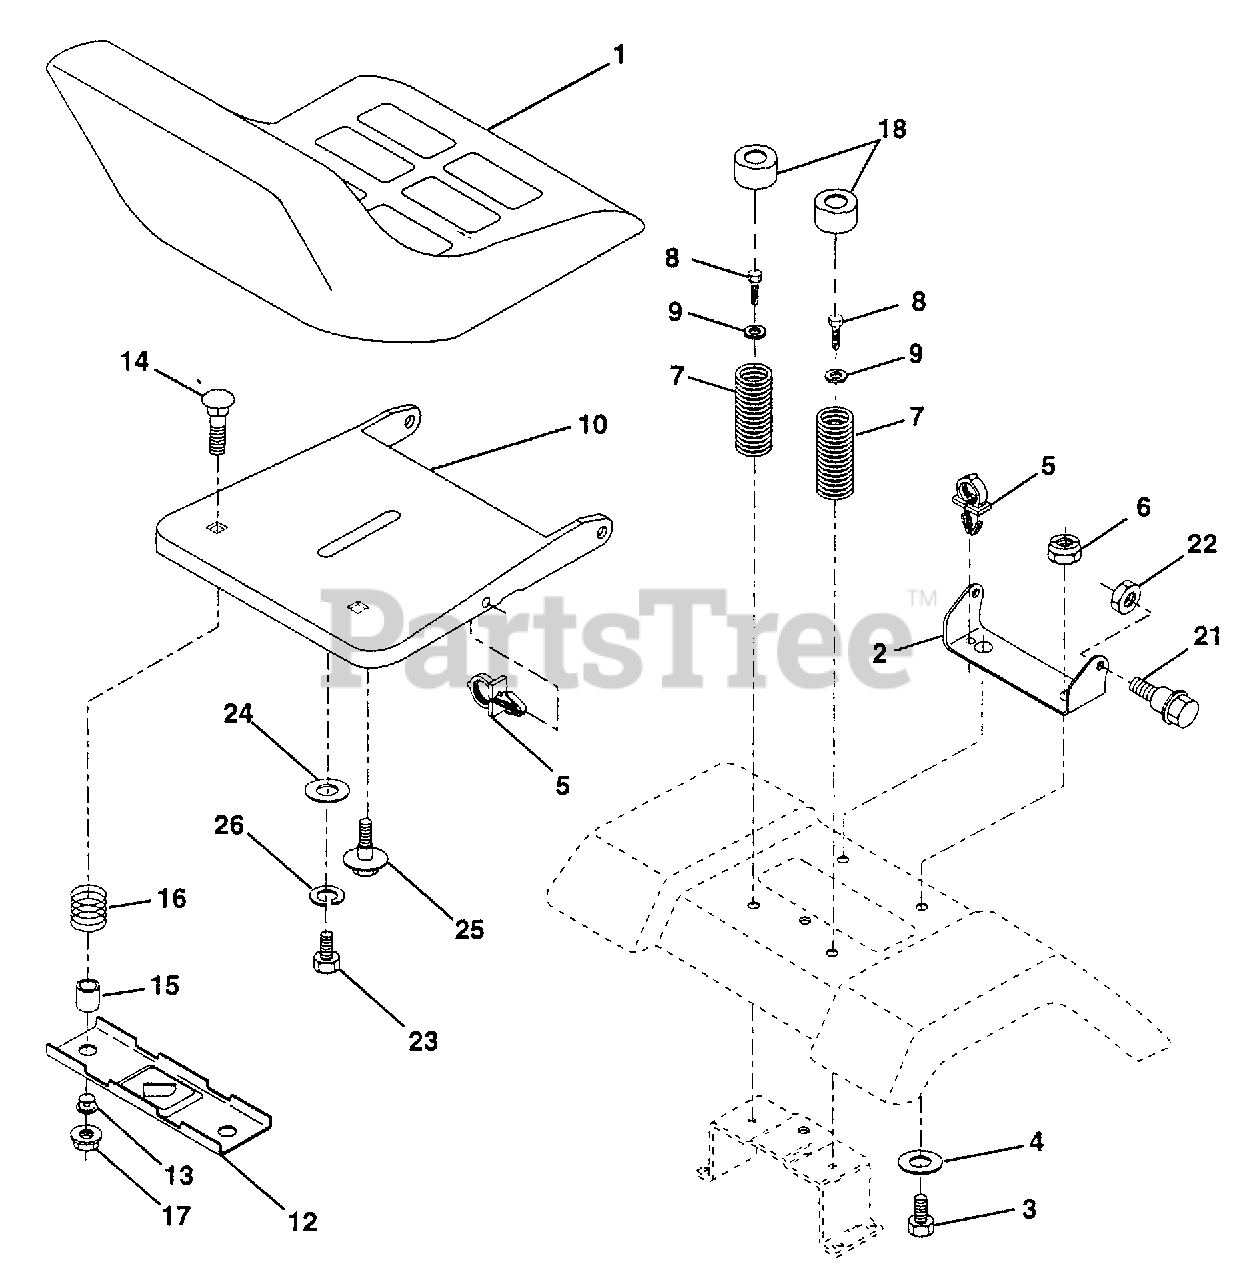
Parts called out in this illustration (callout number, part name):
1	Seat
2	Bracket Pivot Seat 8 720
3	Bolt Fin Hex 3/8-16unc X 1
4	Washer 13/32 X 1 X 10 Ga
5	Clip Push-In
6	Nut Hex w/Ins. 3/8-16 Unc
7	Spring Seat Cprsn 2 250 Blk Zi
8	Screw Thdrol 3/8-16 X 1 Ty-tt.
9	Washer 13/32 X 1 X 14 Ga.
10	Pan Seat
12	Bracket Mounting Switch
13	Bushing Snap Blk Nyl 50 Id
14	Bolt Rdhd Sqnk 1/4-20x1-3/8
15	Spacer Split 28 x .88 Zinc
16	Spring Cprsn Plate
17	Nut Lock 1/4 Lge Flg Gr 5 Zinc
18	Cap Spring Seat
21	Bolt Shoulder 5/16-18 Unc
22	Nut Hex Lock W/Ins 5/16-18
23	Bolt, Hex Head, Fin 1/2-13 x 7/8 Grade 5
24	Washer 17/32 X 1-3/16 X 12 Ga.
25	Bolt Shoulder 5/16-18 X 62
26	Washer Lock
